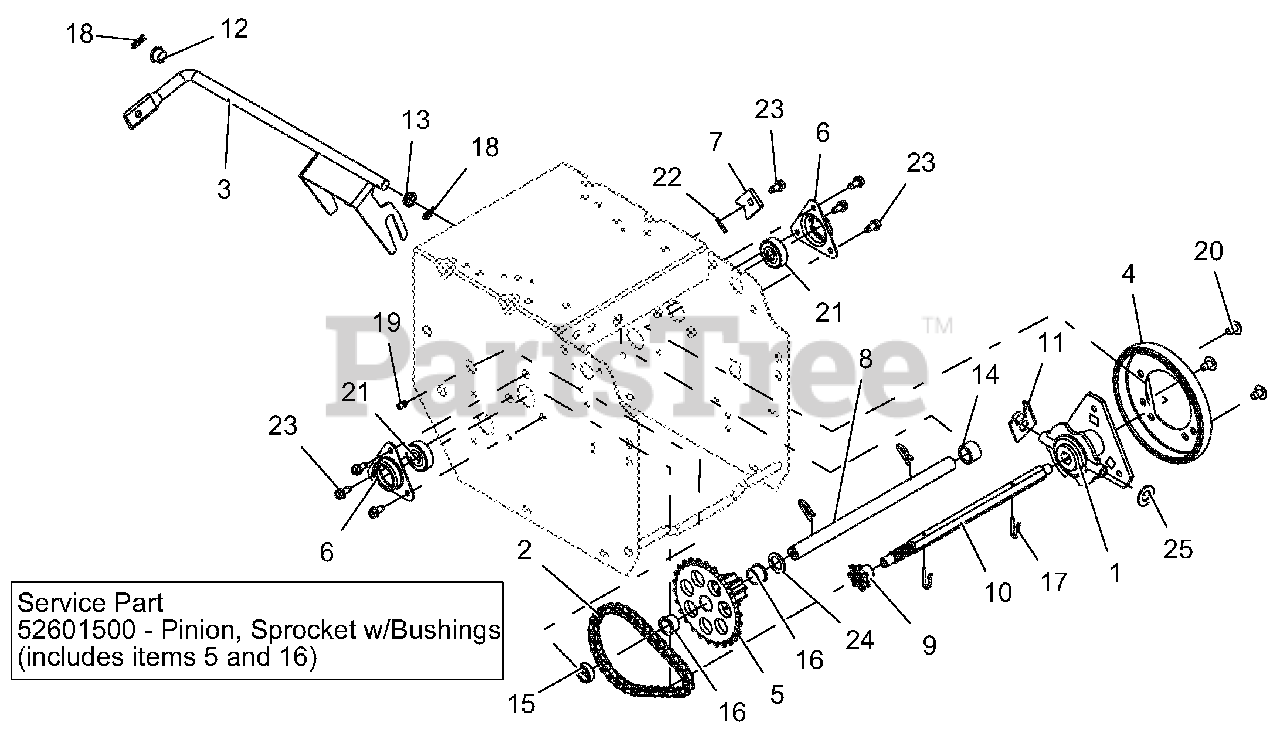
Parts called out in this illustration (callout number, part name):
1	CARRIER, DRIVE DISK
2	CHAIN - #41, 32 PITCHES
3	WELDMENT, SHIFT FORK
4	FRICTION, DISC
5	PINION & SPROCKET
6	FLANGE, BEARING
7	TAB, ANTI ROTATION
8	SHAFT, PINION
9	SPROCKET, PINION 7T W/SPLINE
10	SHAFT, HEX W/SPLINE
11	BRACKET, FORMED - SHIFT FORK
12	BUSHING, POLYLINER-.50 SPLIT
13	BUSHING, POLYLINER-.50 SNAPIN
14	SPACER, .635X.880X.611
15	BSHG-SLV, .635X.880X.305
16	BSHG-FLG .625X.750X.500X.875
17	PIN, SPRING CLIP
18	CLIP, SPRING
19	ZERK,FITTING .25X.125 DRIVE IN
20	SCR-TAP SERRDHDTX .31-18X.50BP
21	BRG-BALL .437X1.375X.437
22	@PIN-GRV .125X1.00 TP E ALLOY
23	SCR-TAP .25-20X.50 HWH TR YWZ
24	WSHR-FL-STL .630X1.005X.062 YZ
25	WSHR-FL-STL .505X1.00X.062YWZC
